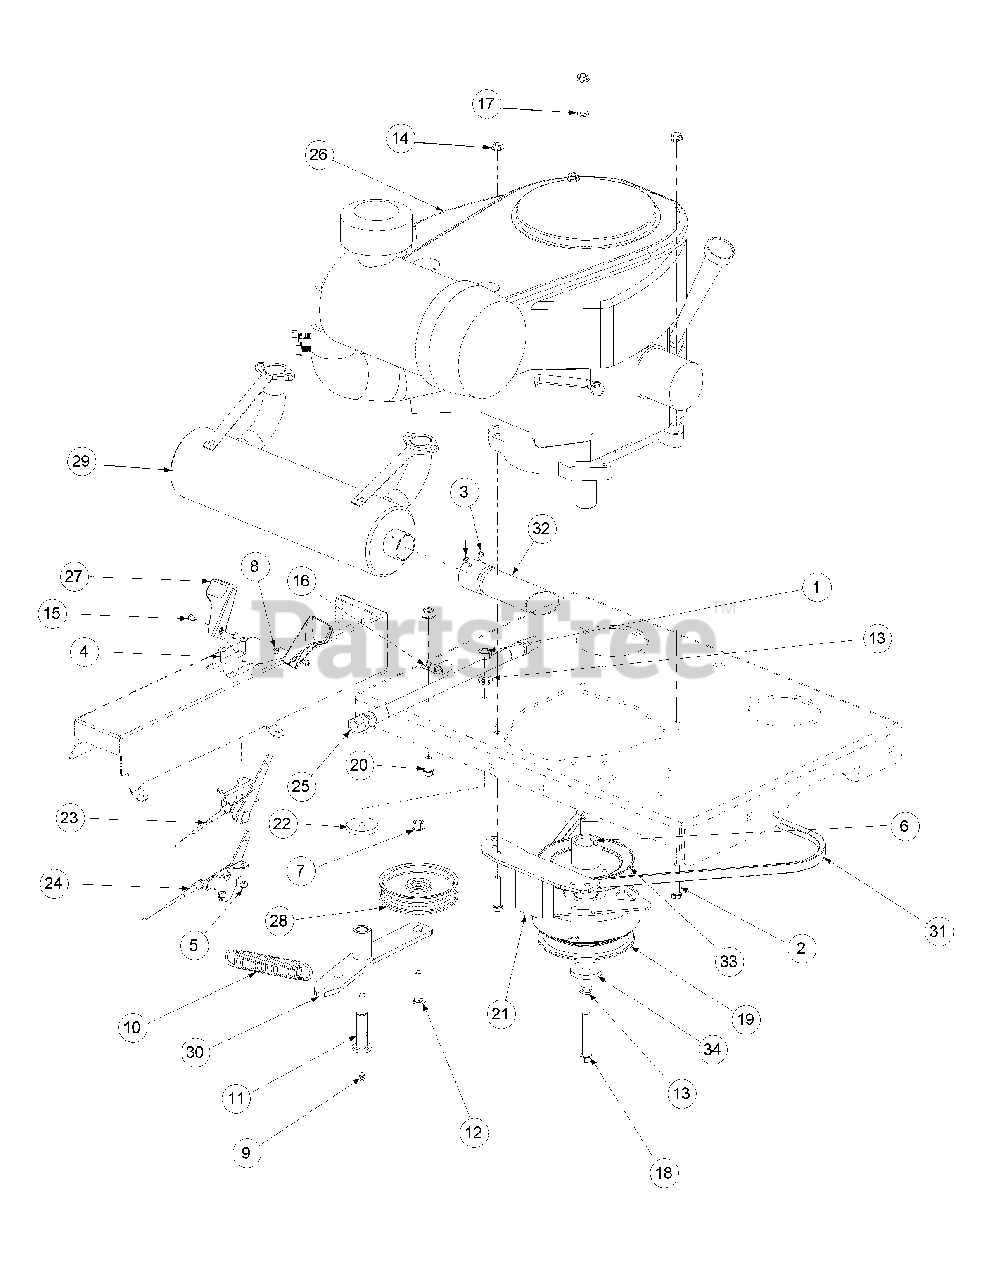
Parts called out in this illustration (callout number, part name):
1	Hex Nut, 7/16-14
2	HHCS, 5/16-18, 1-3/4
3	Screw, #8-32 x 0.375
4	Round Hd. Machine Screw, 10-32 x 3/4
5	Lock Nut, Nylon Insert, 10-32
6	Key, 1/4 x 1/4 x 3
7	Flange Lock, Hex Nut, 3/8-16
8	Nut Washer, W/Star, 8-32
9	Grease Fitting, 1/4-28 x 3/16
10	Extension Spring, .98 OD x 5.00
11	Shoulder Screw, 7/16-14
12	Hex Carriage Screw, 3/8-16, 1.75
13	Lock Washer, 7/16
14	Hexflange Lock Nut, 5/16-18
15	Machine Screw, 8-32, .375
16	Clip, Heat Shield Cable
17	Flat Washer, 5/16
18	Capscrew, 7/16-20 x 2.50
19	Clutch Brake, 1.125 ID
20	Hex Cap Screw, 3/8-16, .750
21	Retainer Clutch Assembly, Ogura
22	Flat Washer, 7/16 ID x 1.75 OD x .25
23	Choke, Control Cable, 43.0
24	Throttle, Control Cable, 39.0
25	Oil Drain Hose
26	25HP Twin Engine, Kawasaki
27	Control Throttle Knob
28	Flat Pulley with Flanges
29	Muffler Accessory, Kawasaki
30	Engine Idler Arm
31	V Belt, A Section x 50.0
32	Muffler Accessory Exhaust Tube
33	Pump Drive Pulley
34	Flat Washer, 7/16 ID x 1.75 OD x .25
